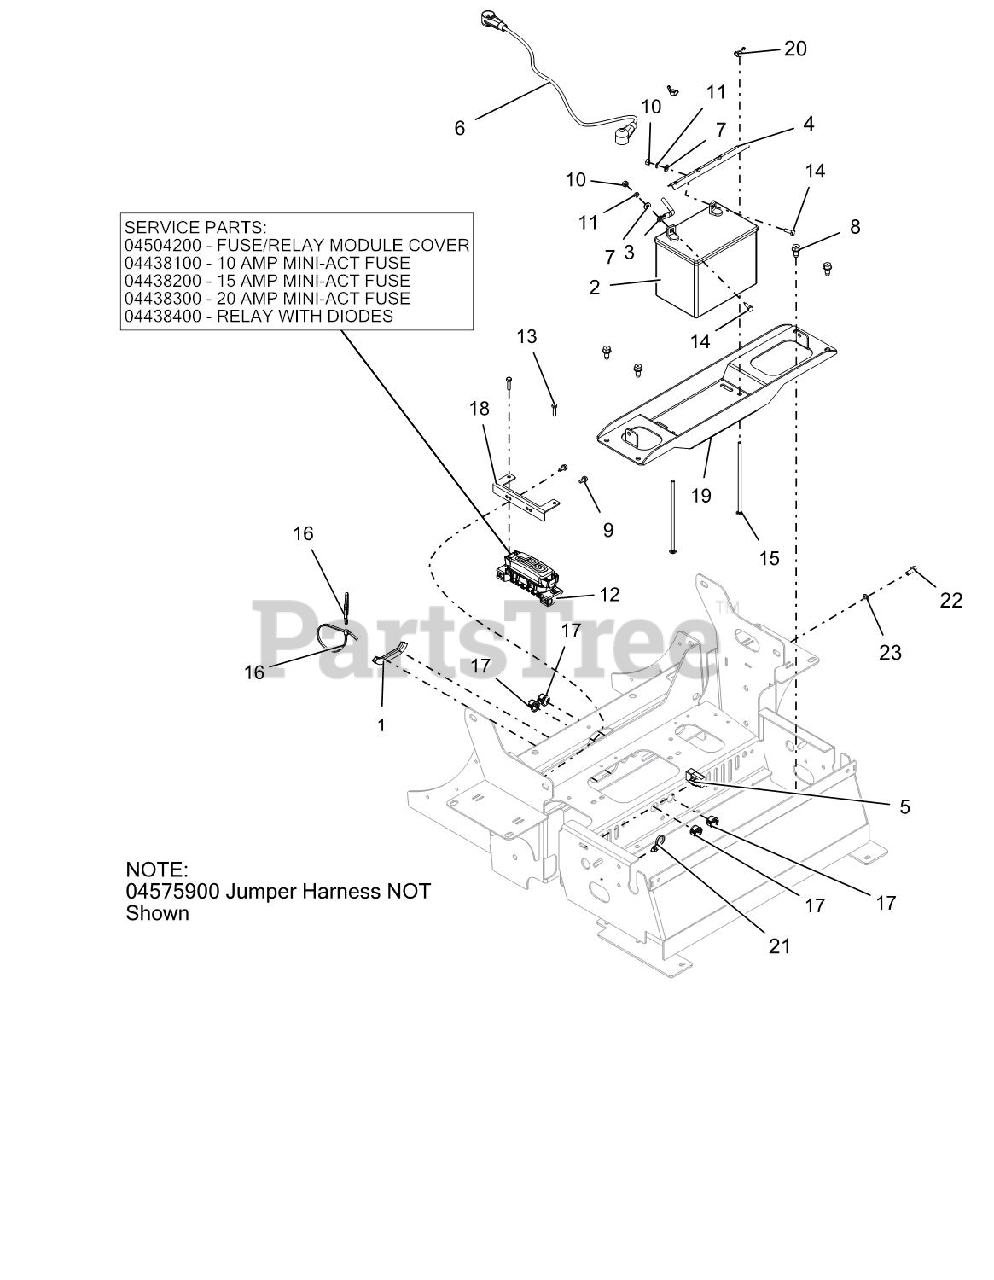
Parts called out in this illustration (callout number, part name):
1	STRIP, COWL
2	BATTERY, 300 CCA 10U1L
3	CABLE-NEGATIVE BATTERY 35.00"
4	HOLD DOWN
5	SWITCH, SNAP IN - N.O./N.O.
6	CABLE - POS BATT W/BOOTS 6X35
7	WSHR-FL-STL.281X.62X.065 YWZC
8	SCR-TAP .38-16X.75 HWH TR YWZ
9	SCR-TAP .25-20X.50 HWH TR YWZ
10	NUT-HEX .25-20 YWZC
11	WSHR-LK .25X.062 REG YWZC
12	FUSE,10 AMP MINI-ATC
12	FUSE,20 AMP MINI ATC
12	RELAY,MICRO5 TERMINAL W/DIODES
12	COVER, HARNESS FUSE/RELAY MOD
12	FUSE,15 AMP MINI-ATC
12	HARNESS, PT400 WIRING
13	BLT-HEX M6-1.0X25 YWZC
14	BLT-HEX .25-20X.75 GR5 YWZC
15	BLT-RDHDSQNK .25-20X7.50 GR2YZ
16	CABLE TIE LG 5-1/2
17	BUSH, PANEL SNAP .687X.875X.56
18	FUSE HOLDER MOUNTING BRKT -RED
19	PT400 GAS BATTERY TRAY - RED
20	NUT-LK WING .250-20 YWZC
21	CABLE TIE W/ TREE (.25 HOLE)
22	BLT-HEX M8-1.25X20 YWZC
23	WSHR-LK .31X.078 REG YWZC
